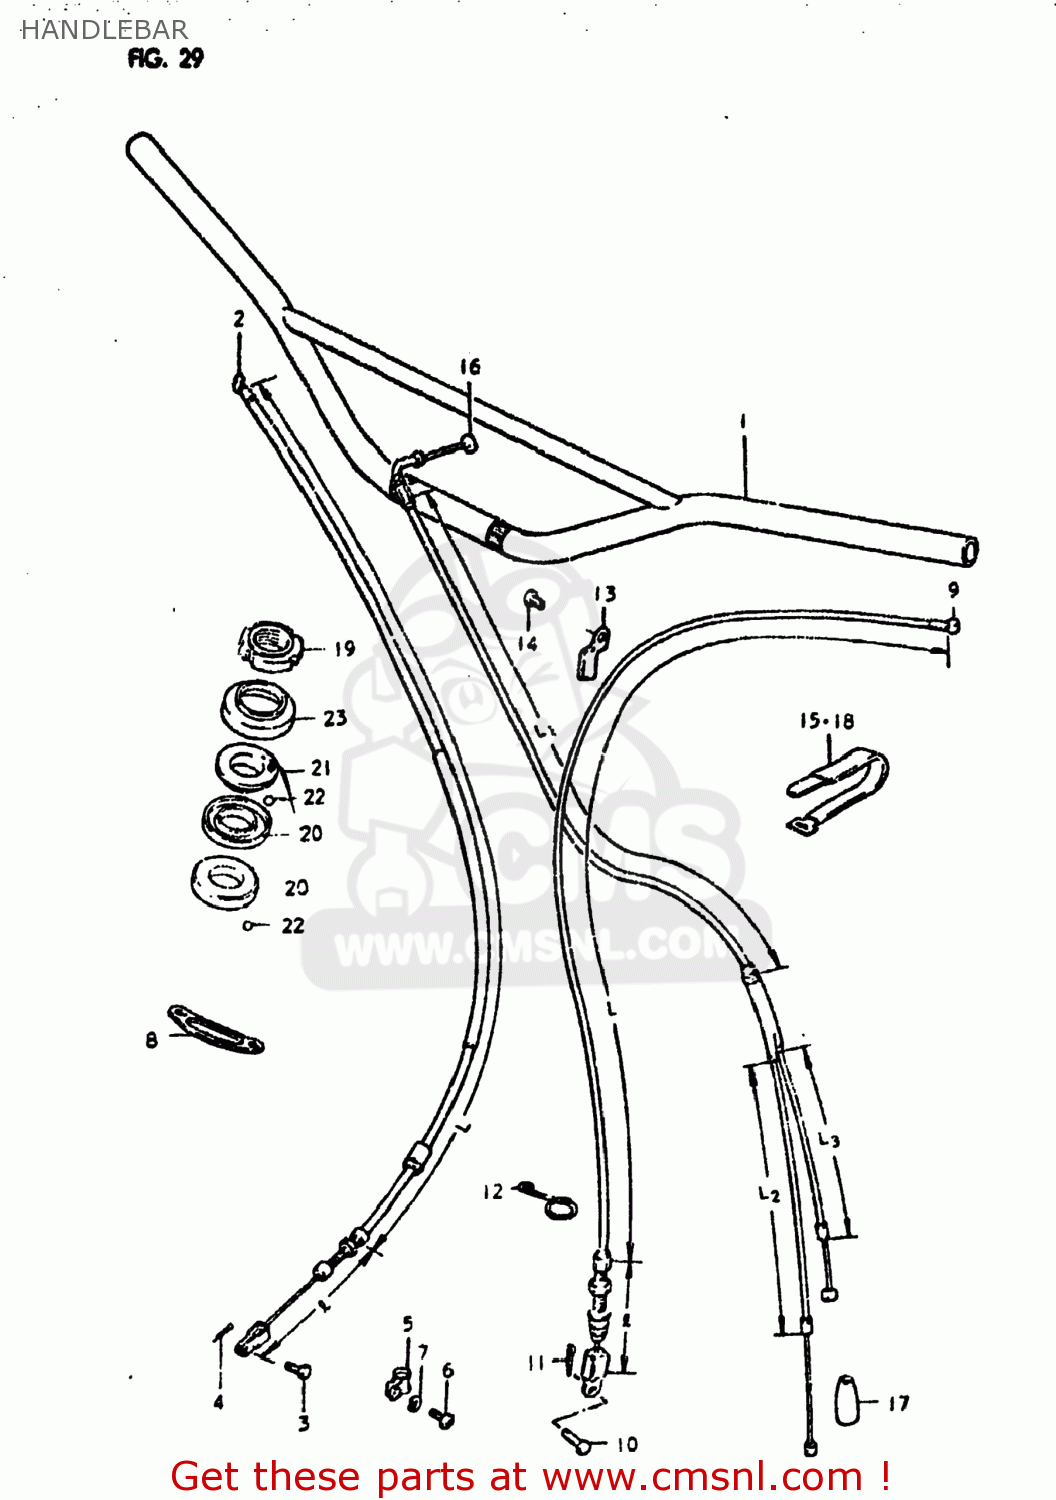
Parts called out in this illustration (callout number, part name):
1	HANDLEBAR
2	CABLE ASSEMBLY,FRONT BRAKE
3	PIN(L:17.5)
4	PIN
5	GUIDE,CABLE
6	SCREW
7	LOCK WASHER
8	GUIDE,CABLE
9	CABLE ASSY,CLUTCH
10	PIN(L:15)
11	PIN
12	CLIP
13	CLAMP
14	SCREW
15	CLAMP
16	CABLE ASSEMBLY,THROTTLE
17	SEAL,DUST(7X18X30)
18	CLAMP
19	NUT,STEERING STEM(25X44X10)
20	LACE,STEERING INNER LWR
21	LACE,STEERING OUTER UPR
22	BALL
23	DUST SEAL,STEERING UPR
